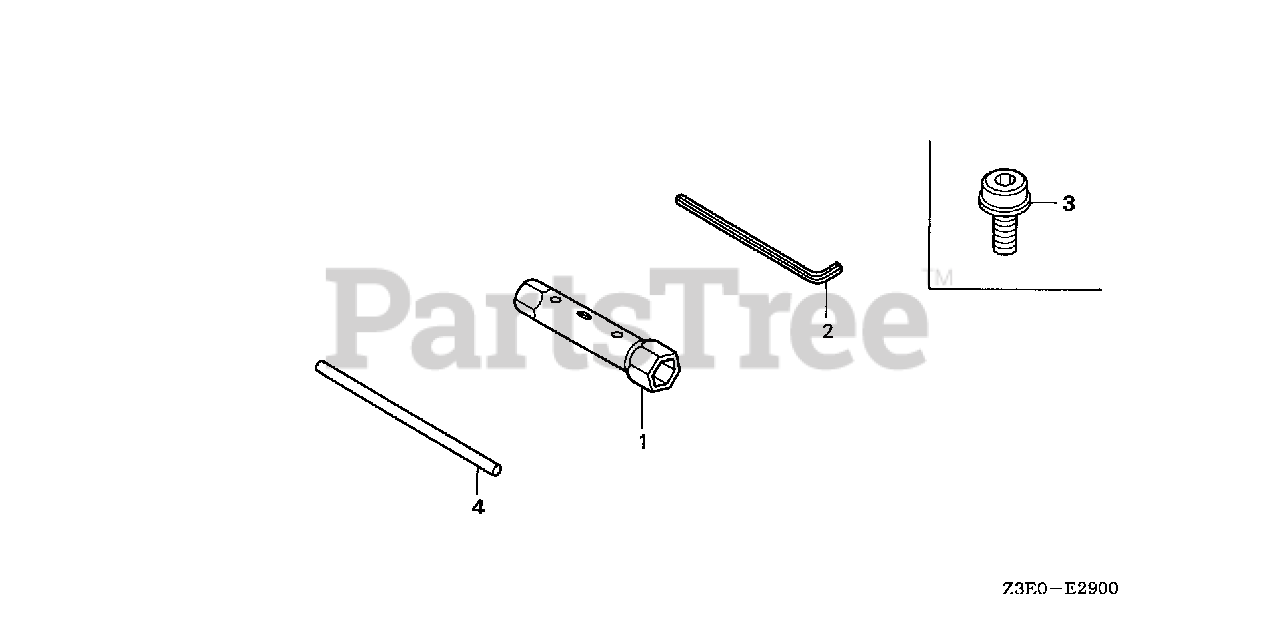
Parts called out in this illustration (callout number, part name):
1	WRENCH, PLUG (16X19)
2	WRENCH, HEX. (4MM)
3	BOLT, SOCKET (5X9)
4	BAR A, HANDLE
